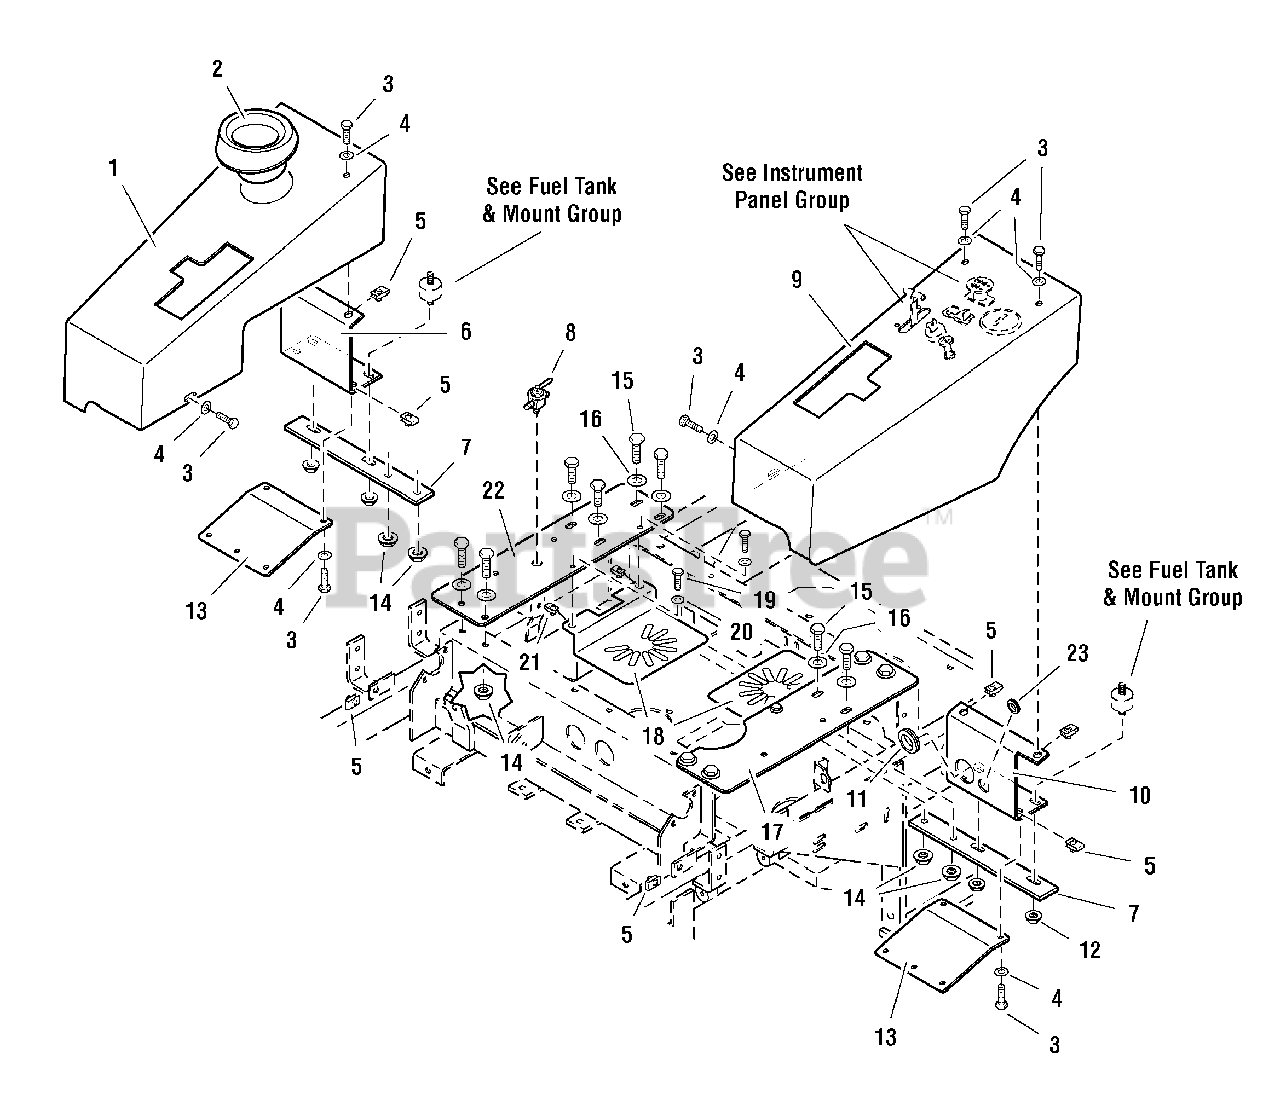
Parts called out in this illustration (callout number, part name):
1	CONTROL COVER-RH
3	CAPSCREW, Hex Hd, 5/16-18 x 1
4	WASHER, 5/16
5	BODY CLIP, 5/16-18
6	CONTROL COVER MOUNT-RH
7	TANK MOUNT BAR
8	FUEL SHUT OFF VALVE
9	CONTROL COVER-LH
10	CONTROL COVER MOUNT-LH
12	NUT, Hex, Serrated Flange, 5/16-18
13	DEBRIS GUARD
14	NUT, Hex, Serrated Flange, 3/8-16
15	CAPSCREW, Hex Hd, 3/8-16 x 3/4
16	WASHER, 3/8
17	COVER MOUNT-LH
19	BOLT, 1/4-20 X 1", GD
20	WASHER, 1/4 SAE (5025154)
21	BODY CLIP, 1/4-20
22	COVER MOUNT-RH
